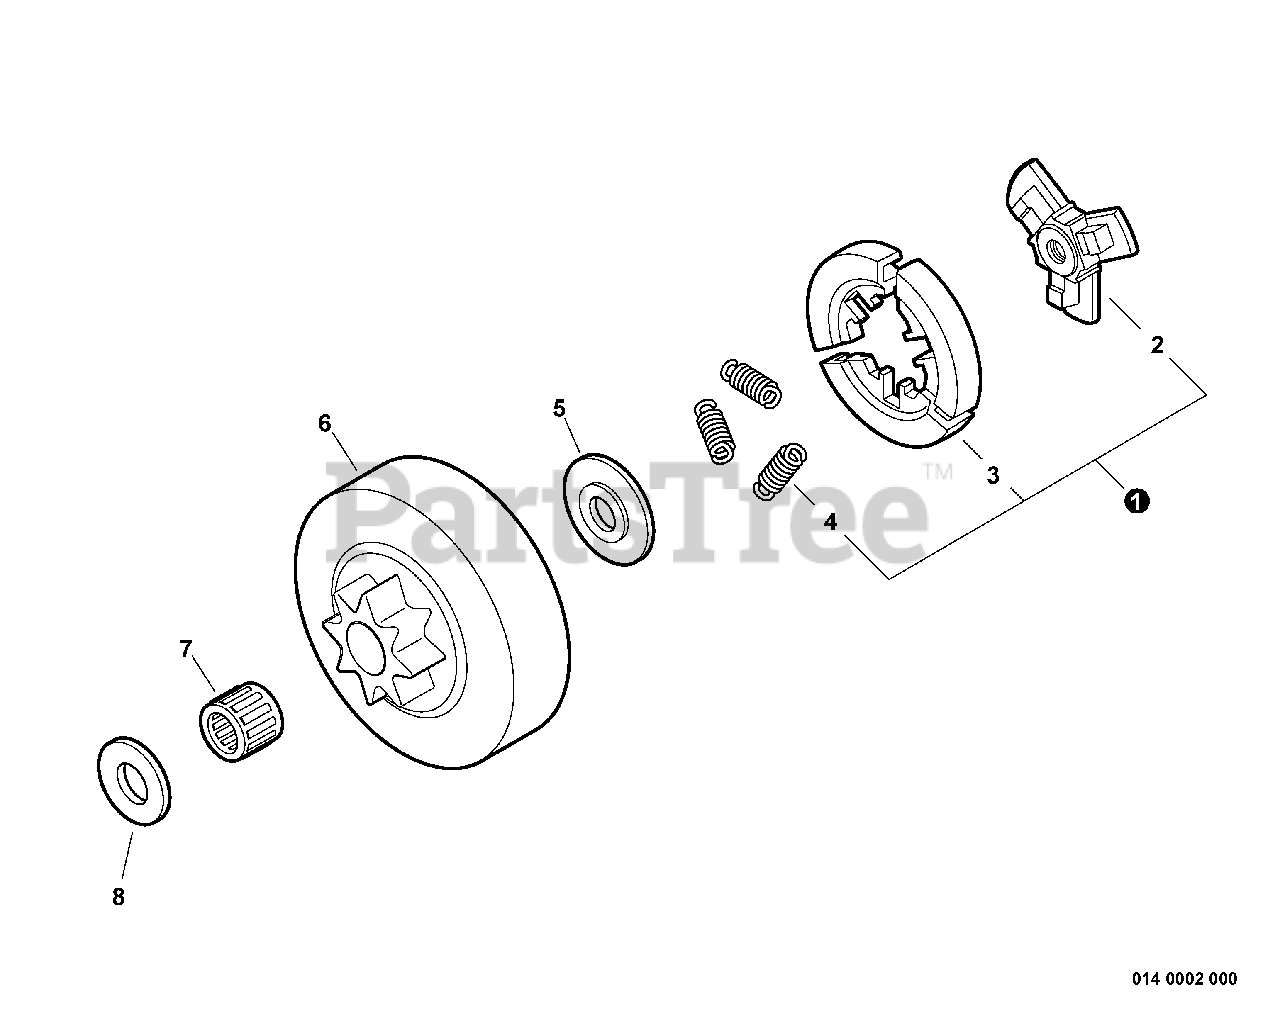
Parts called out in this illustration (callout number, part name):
1	CLUTCH ASSY
2	HUB, CLUTCH
3	SHOE SET, CLUTCH (3PCS)
4	SPRING, CLUTCH
5	PLATE, CLUTCH
6	DRUM, CLUTCH 3/8"
7	BEARING, NEEDLE 10×13×10
8	WASHER 10.2×24.5×1.2
